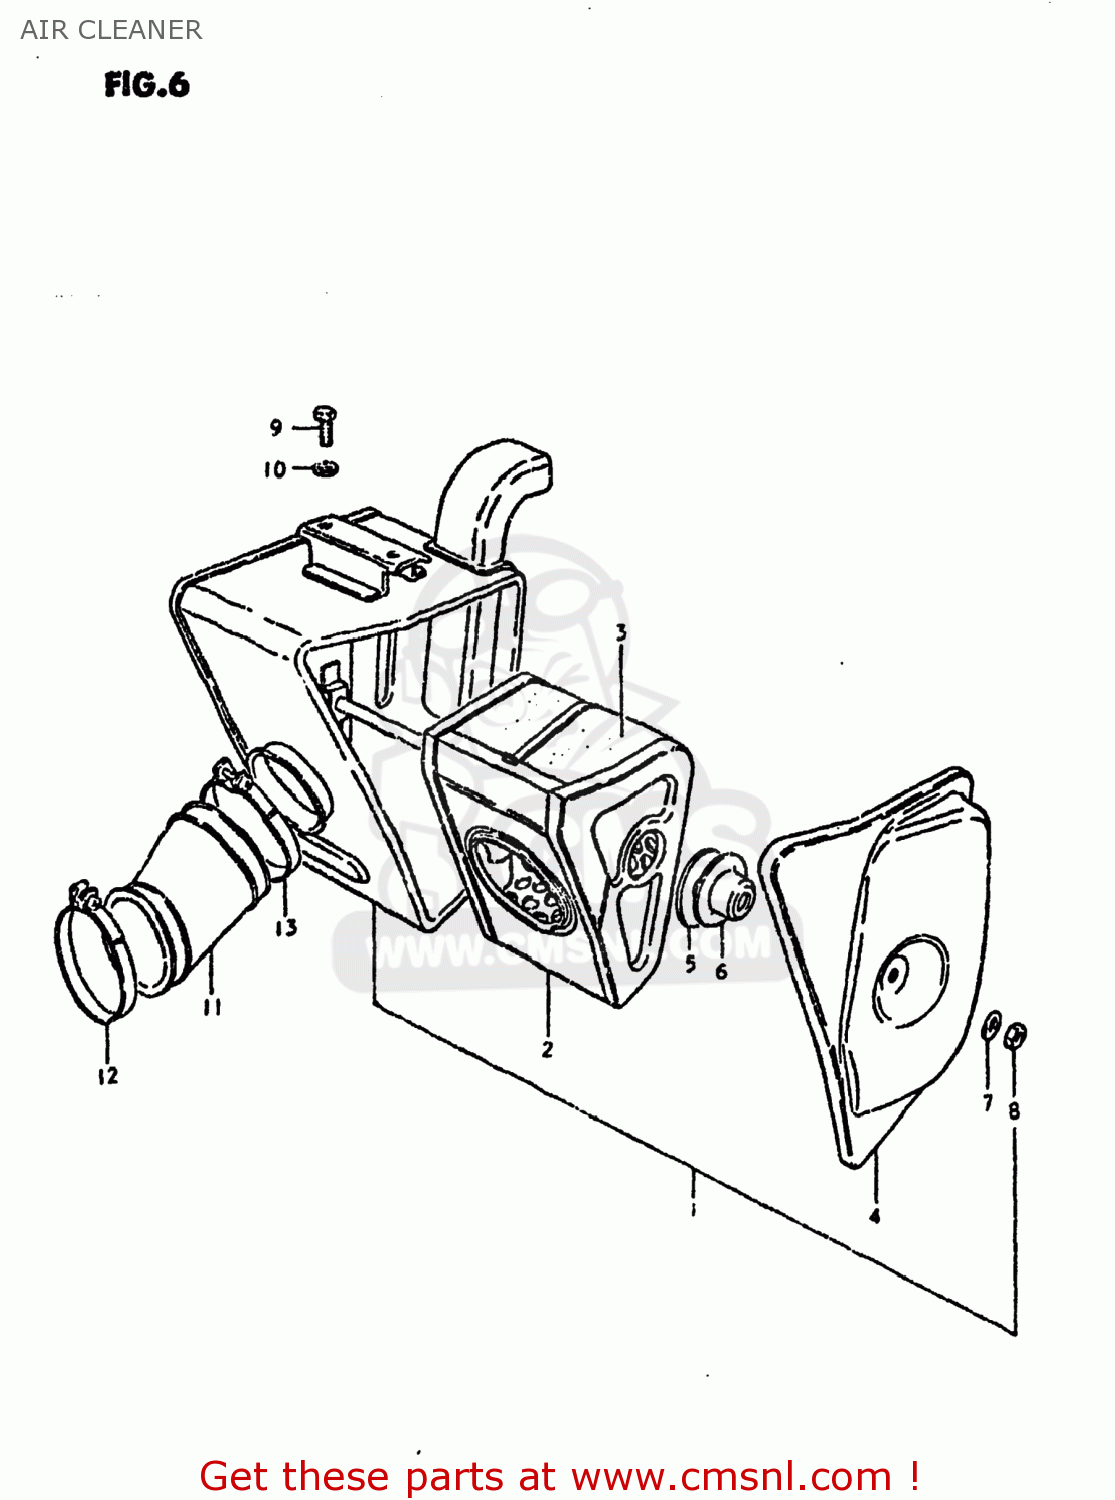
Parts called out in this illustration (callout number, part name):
1	CLEANER ASSEMBLY,AIR
2	FILTER ASSY,AIR CLEANER
3	FILTER
4	CAP
5	WASHER,AIR CLEANER ELEMENT
6	SPACER
7	WASHER
8	NUT
9	BOLT
10	WASHER
11	HOSE,CARBURETOR AIR INLET
12	CLAMP
13	CLAMP
